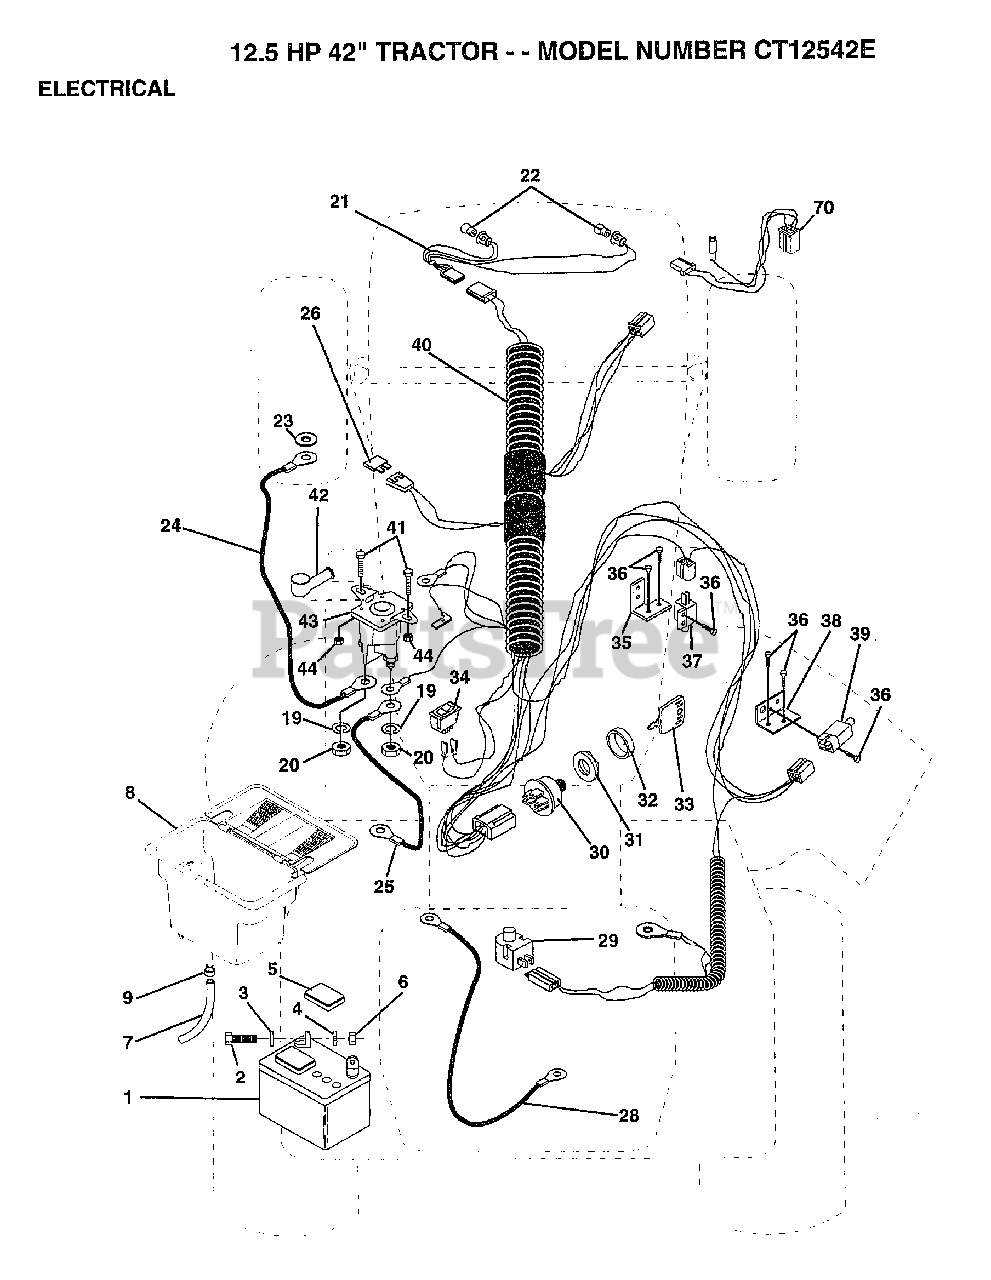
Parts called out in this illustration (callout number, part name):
2	BOLT LT
3	WASHER
4	LOCKWASHER
5	"CAP,BATTERY "
7	TUBE T
9	HOSE CLAMP T
20	NUT
21	"HARNESS,LIGHT SOC"
22	HEADLAMP BULB
23	LOCKWASHER
24	"CABLE T, BATTERY"
26	FUSE HYT
28	CABLE T
29	SWITCH SEAT
32	COVER KEY SWITCH
33	KEY MLD GEN DELTA
34	SWITCH LT
35	BRACKET LT
36	SCREW
37	SWITCH-INTER. GT
38	BRACKET SWITCH IN
39	SWITCH INTERLOCKT
40	HARNESS IGN DASH
41	BOLT HXHD FIN
44	NUT HXKEP 1/4X20
70	HARNESS ENG DUAL
